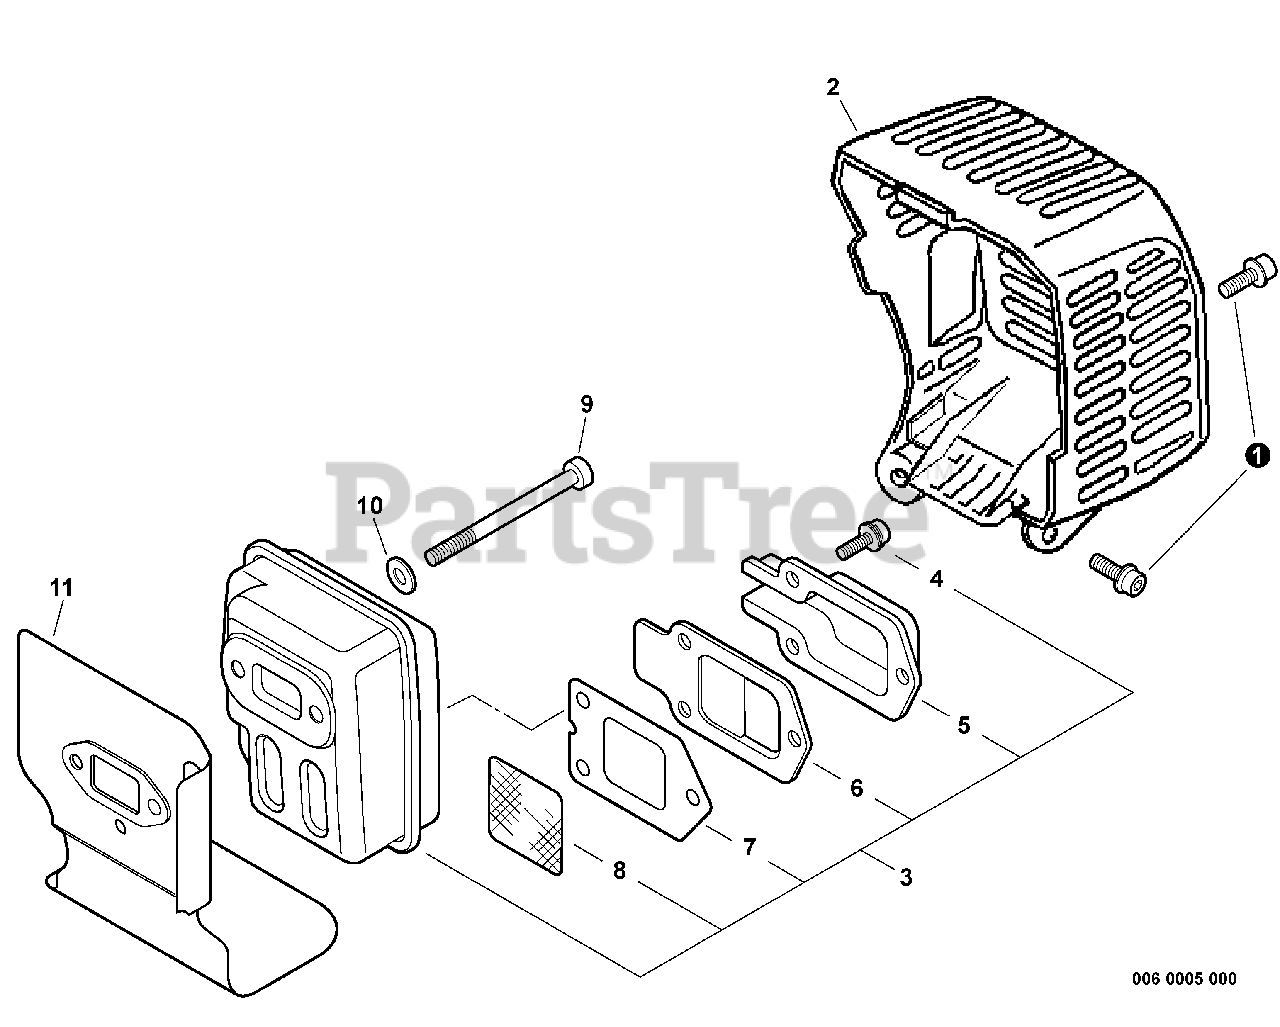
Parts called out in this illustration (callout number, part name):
1	COVER, EXHAUST
2	SCREW - 5X12
3	MUFFLER ASSY
4	SCREW - 4X10
5	GUIDE, EXHAUST - OUTER
6	GASKET, EXHAUST - INNER
7	GASKET, EXHAUST
8	SCREEN, SPARK ARRESTOR
9	SCREW - 5X55
10	WASHER - 5
11	SHIELD, EXHAUST
